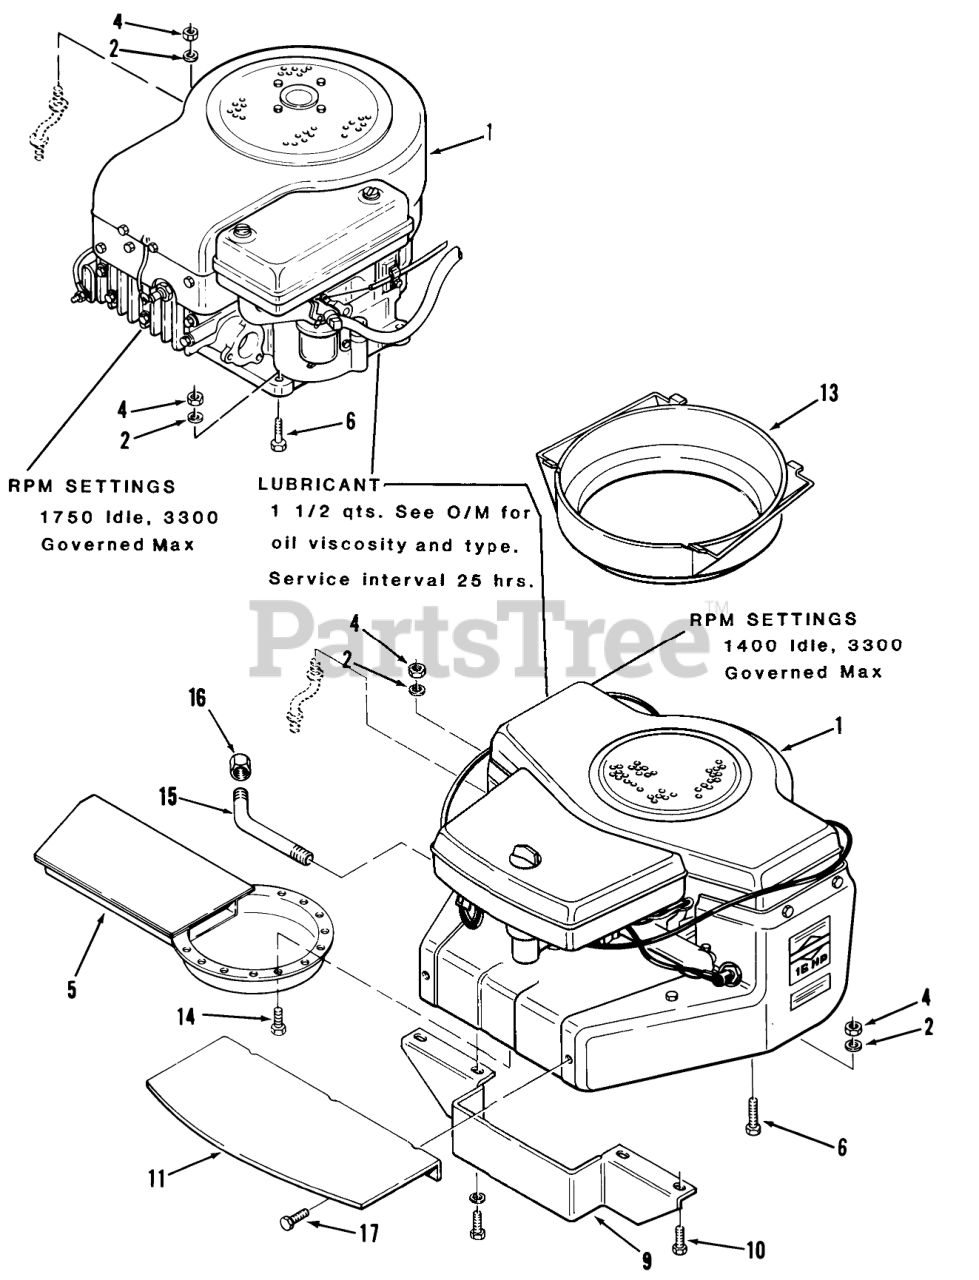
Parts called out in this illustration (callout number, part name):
1	Engine-11HP-B&S Model 253707, Type 0131-01-B-115 Only
1	Engine-16HP-B&S Model 402707, Type 0130-05 216-5 Only
2	WASHER 5/16 SAE
4	Nut
5	Exhaust Deflector B-165 Only
6	Bolt
6	HHCS
9	Duct-Rear 216-5 Only
10	Bolt
11	Duct-Front B-165 Only
13	DUCT-AIR INTAKE
14	SCREW 8-32X3/8
16	Cap
17	Screw-Hex HD Slotted
